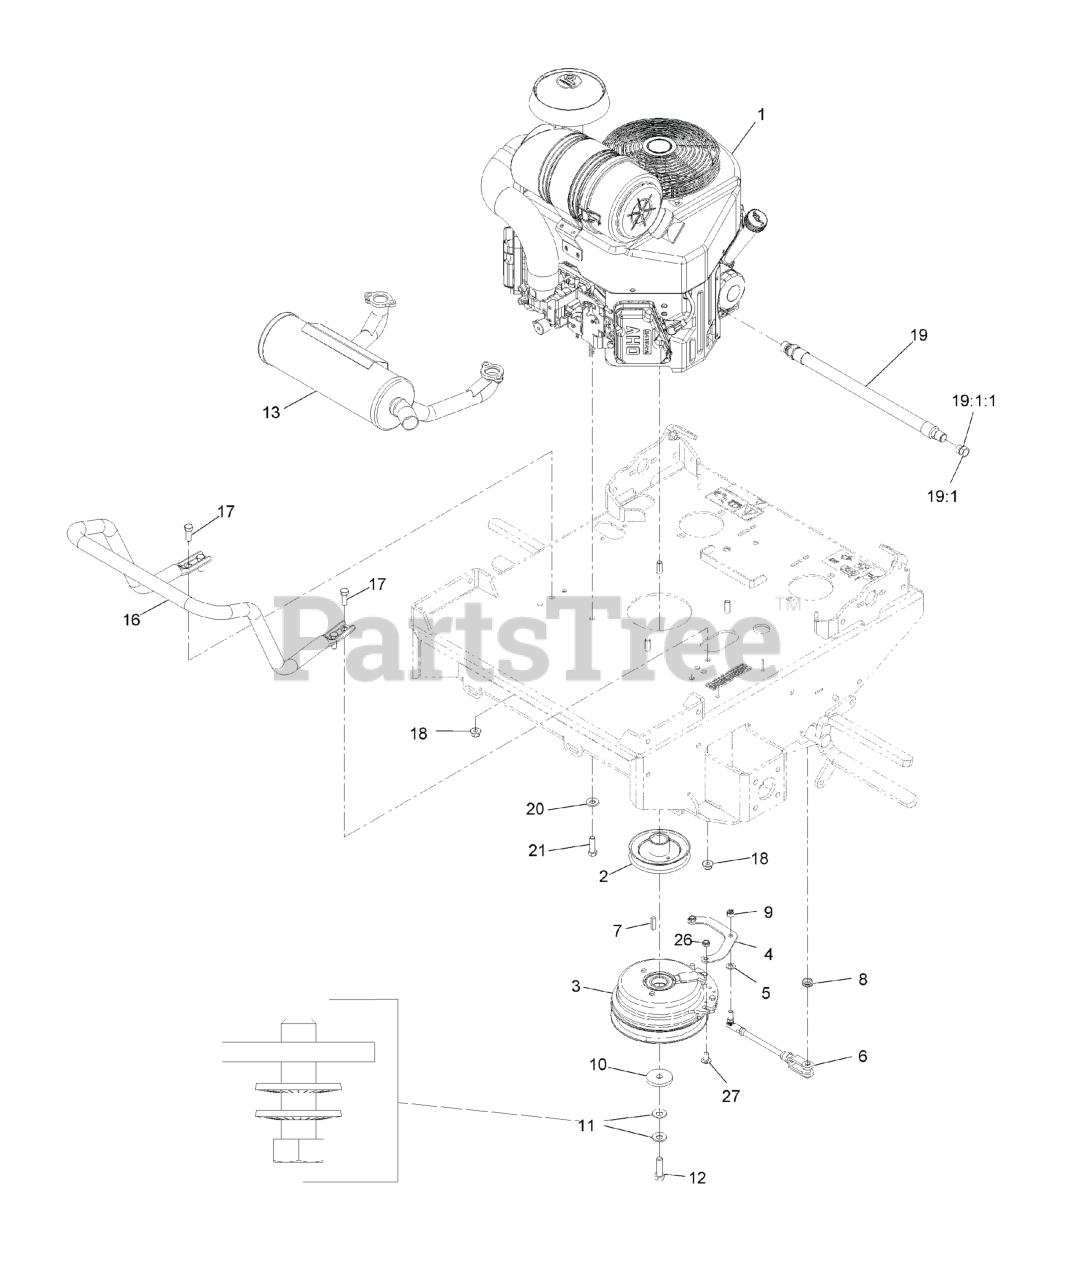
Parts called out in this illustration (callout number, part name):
2	SHEAVE W/ HUB
3	CLUTCH, 200 FT/LBS, 1.13
4	STRAP, CLUTCH
5	WASHER-PLAIN
6	ASM, CLUTCH ANCHOR
7	KEY
8	GROMMET
9	NUT-LOCK
10	WASHER-CLUTCH
11	WASHER-SPRING
12	BOLT-HEX, TAP
13	MUFFLER,HORIZONTAL
16	GUARD-MUFFLER
17	SCREW-HH
18	NUT-HF, NI
19	ASM, ENGINE OIL DRAIN HOS
19:1	PLUG-HH
19:1:1	O-RING
20	WASHER-BELLEVILLE
21	SCREW-HH
26	NUT-LOCK, NI
27	SCREW-CARR
